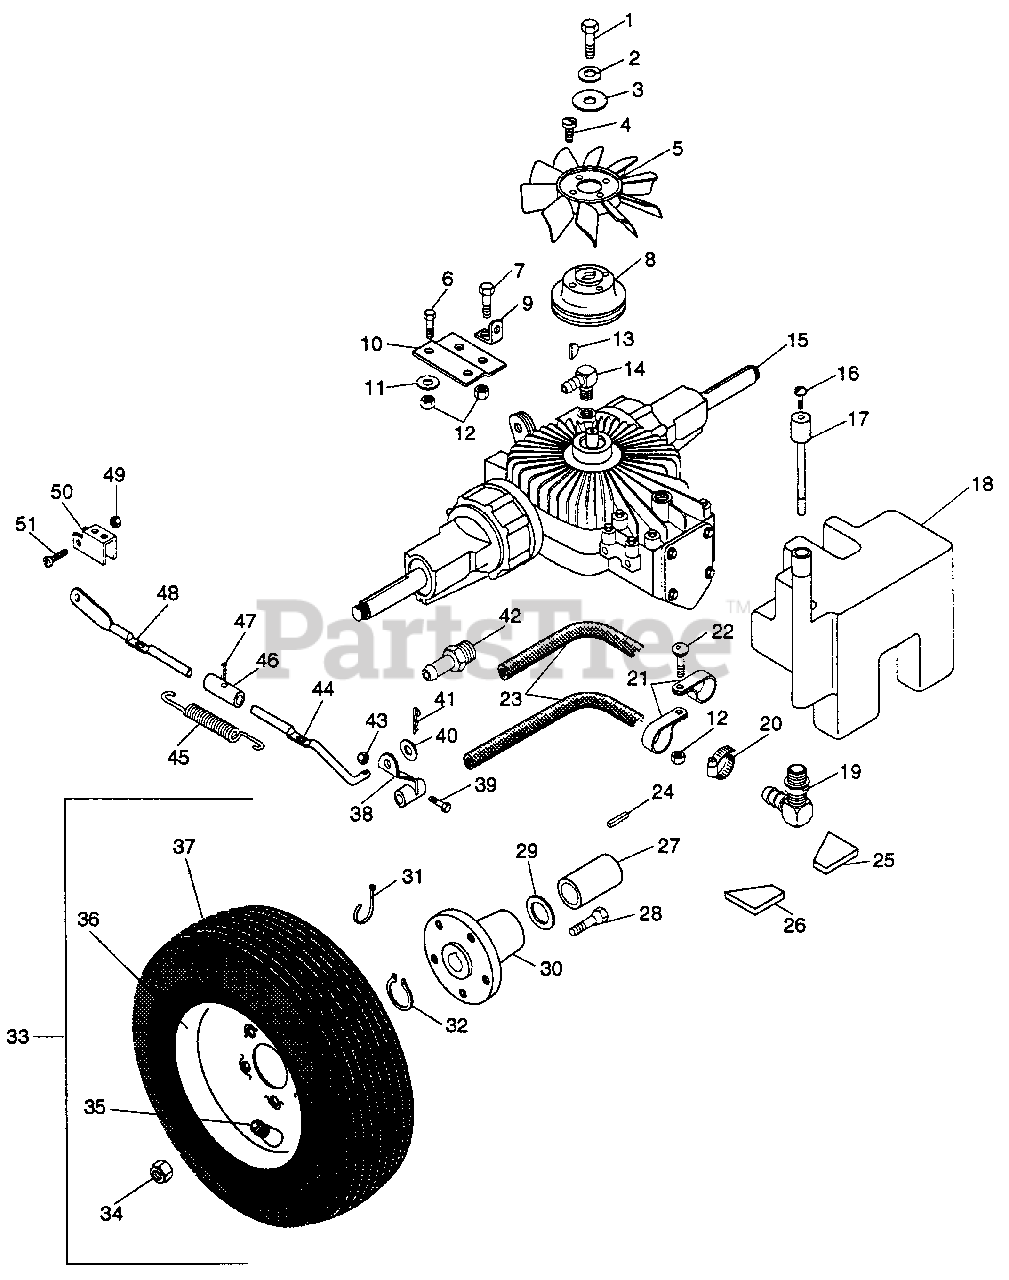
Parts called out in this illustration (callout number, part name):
1	Blt-Hex .25-20 x .75 Pl Gr 5
2	Wshr-Lock .250 Reg.
3	Wshr-Fl-Stl .281 x 1.5 x .120
4	Scr-Mch 10-24 x .50 Phd
5	Fan
6	Blt-Hex .380-16 x .875
7	Blt-Hex .38-16 x 3.25 Pl Gr 5
8	Transaxle Sheave
9	Spring Anchor
10	Bracket
11	Washer, Flt .375 x 1.125 x .065
12	Nut-Lk-Nyl .375-16 Pl
13	Key, Wdrf 3/16 x 5/8 Hrd #61
14	Fitting
15	Transaxle
16	Scrw-Vent Sl 8-32 x .250
17	Dipstick
18	Tank, Hydraulic
19	Ftg .88-14 x .63
20	Hose Clamp
21	Clamp, Steel 1.0
22	Blt-Rdhdsqnk .38-16 x 1.0 Pl
23	Hose
24	Key-Str .25 x 2.0 x .25
25	Pad, Tank LH
26	Pad, Tank RH
27	Spacer
28	Blt-Lug Sernkhdnd .44-20 x 1.188
29	Wshr-Thrst 1.55 x 1.002 x .093
30	Wheel Hub
31	Clamp, Universal
32	Rg-Rtng-Ext 1.00 x .078
33	T/Whl Assy 23 x 8.50-12
34	Nut-Lug .437-20 Pl
35	Valve Stern Ass'y
36	Wldmt, Rim
37	Tire, Rear 23 x 8.50 - 12
38	Arm-Dump Valve
39	Blt-Hex .25-20 x 1.00 Pl Gr 5
40	Wshr-Fl-Stl .406 x .812 x .065 Pl
41	Pin-Cotr .09 x .75 Pl
42	Ftg-Adptr 88-14
43	Nut-Lk-Nyl .250-20 Pl
44	Pin
45	Sg-Tens .090 x .96 x 4.0 Wld 23
46	Collar
47	Pin, Roll .125 x .625
48	Rod
49	Nut-Lk 10-24 Ny Pl
50	Hour Meter
51	Scr-Mch 10-24 x 1.00 Phcr
